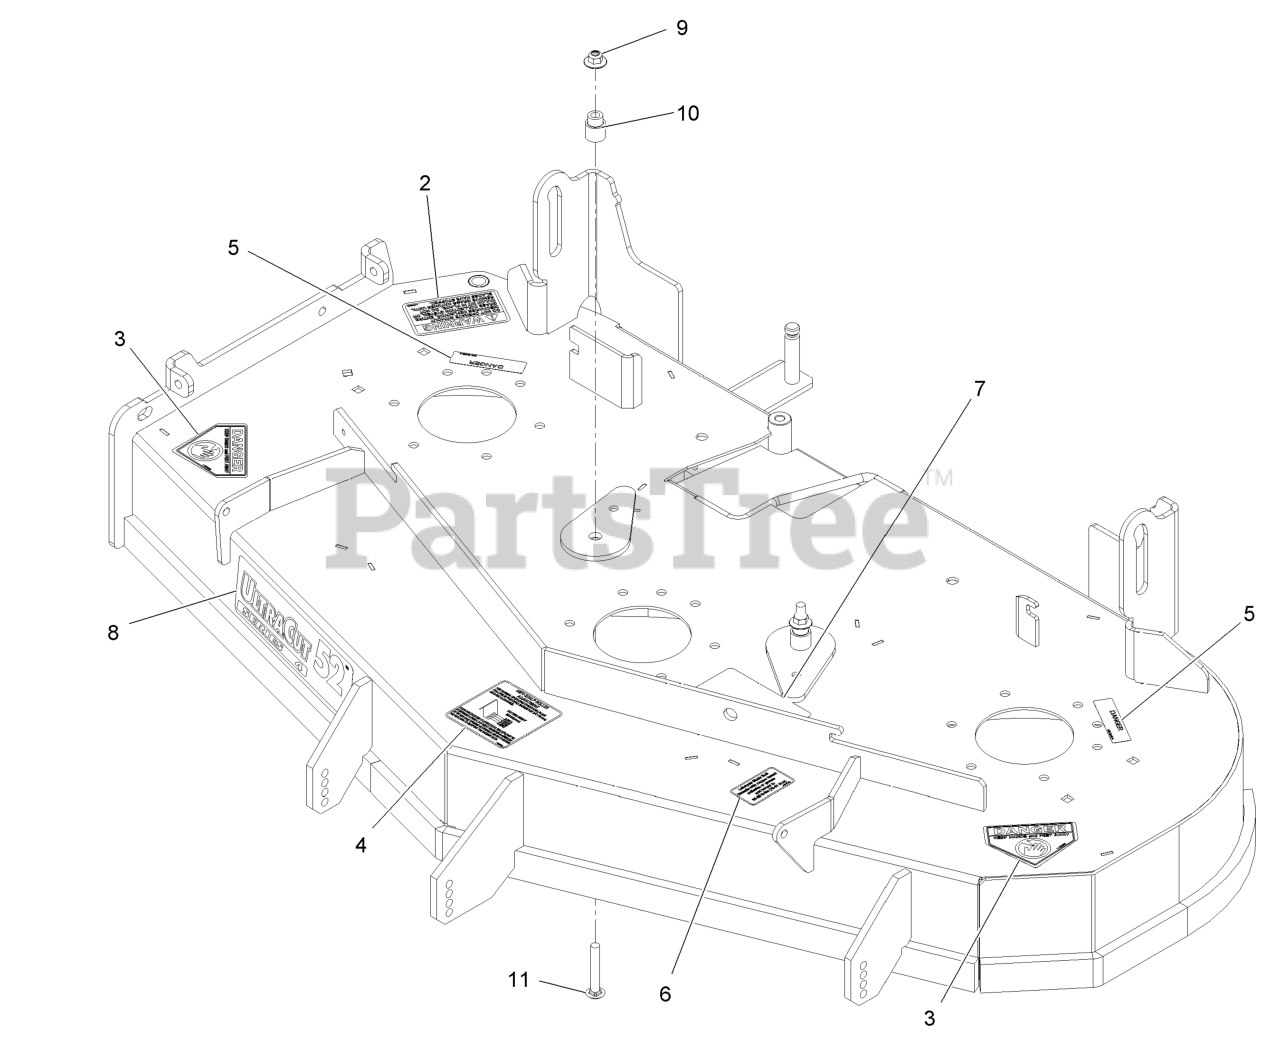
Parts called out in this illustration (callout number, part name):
2	DECAL-WARNING, DISCHARGE
3	DECAL-DANGER
4	DECAL,ANTISCALP
5	DECAL-COVER, MISSING
6	DECAL,BOLT TORQUE
7	DECAL-BELT ROUTING
8	DECAL,ULTRACUT 52 SERIES
9	Nut-Nyloc 3/8-16 Flg
10	BUSHING-IDLER
11	SCREW-CARR
